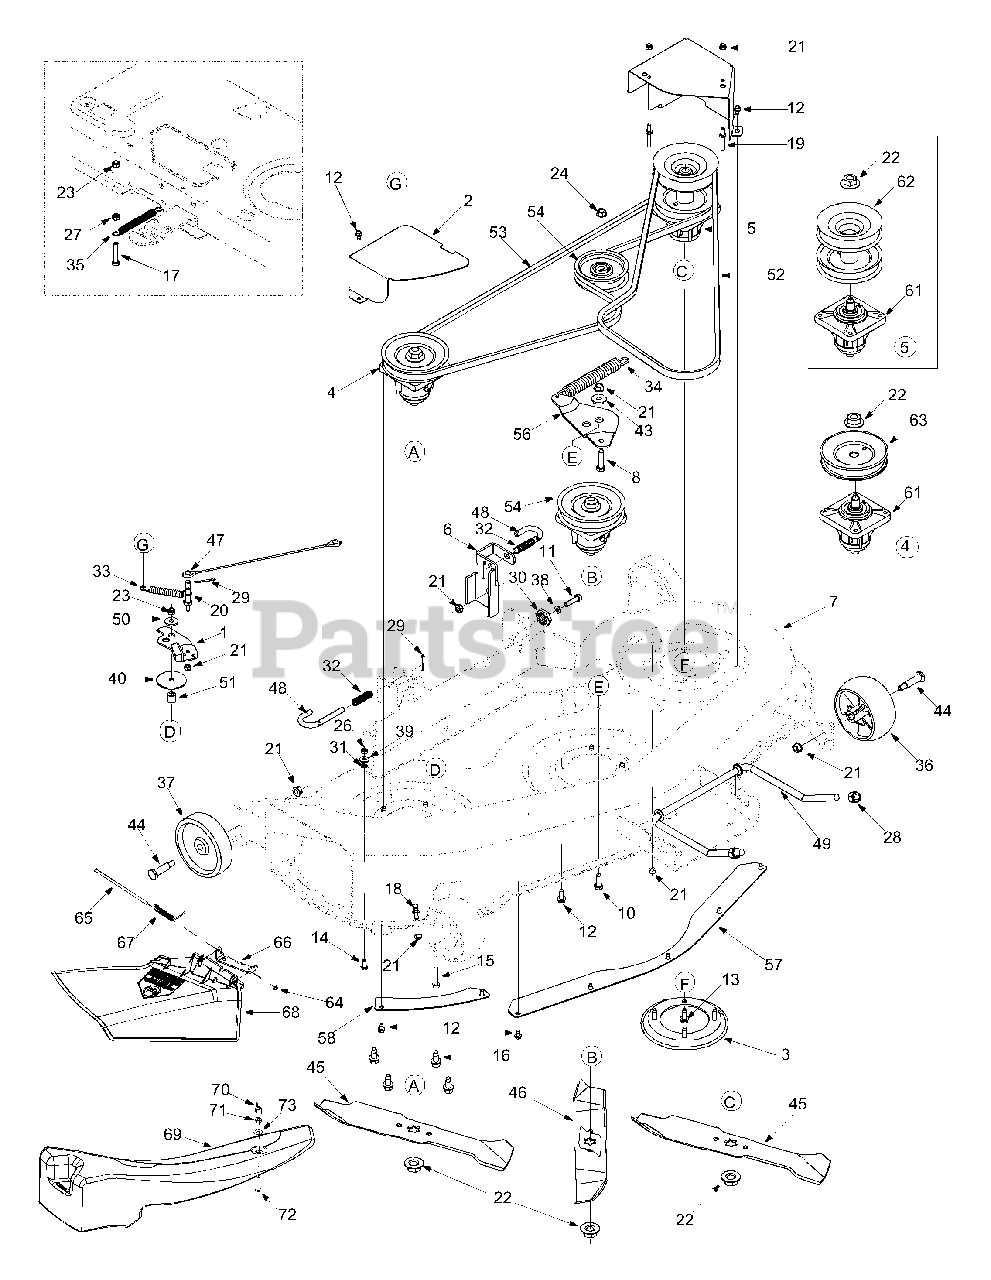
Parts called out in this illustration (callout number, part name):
1	Deck Brake Assembly
5	Spindle Assembly: Double Pulley
9	Hex Bolt 1/4-20 x 2.0
10	Hex Bolt 3/8-16 x 1.0
11	Hex Bolt 5/16-18 x 1.25
12	TT Screw 1/4-20 x 0.5
13	TT Screw 5/16-18 x 0.875
14	Hex Bolt 1/4-20 x 0.620
15	Hex Bolt 5/16-18 x 1.5
16	LD Screw 5/16-18 x 0.75
17	Hex Bolt 5/16-18 x 1.75
18	Grass Catcher Pin
19	Belt Guard Pin
20	Pin 1/4-20
21	Hex Lock Nut 1/4-20
22	Flange Nut
23	Lock Nut 5/16-18
24	Flanged Lock Nut 3/8-16
25	Hex Nut M16
26	Hex Nut 1/4-20
27	Hex Nut 5/16-18
28	Lock Nut 1/2-13
29	Cotter Pin
30	Gear: Deck Adjustment
31	Push Nut
32	Compression Spring
33	Extension Spring
34	Extension Spring
35	Extension Spring
36	Deck Wheel 5.0 dia. Ball
37	Deck Wheel 5.0 x 1.38
38	Lock Washer
39	Bell Washer
40	Flat Washer
41	Lock Washer
43	Shoulder Spacer
44	Shoulder Screw 3/8-16
45	Blade: 16.28" Three in One
46	Blade: 14.88" Three in One
47	Cable: Bracket
48	Rod: Deck Release Handle
49	Rod: Front Adjustment
50	Shoulder Spacer
51	Spacer
52	Belt: V Type (two belt deck design)
53	Belt: V Type (two belt deck design)
54	Idler Pulley
55	Label: Danger Tag
59	Chute Stop
61	Spindle Housing
62	Deck Pulley: Double
63	Deck Pulley
64	Speed Nut
65	Hinge Pin
66	Mounting Bracket
67	Torsion Spring
68	Chute Deflector: Side Discharge
69	Mulch Plug
70	Wing Nut
71	Hex Nut
72	Machine Screw
73	Flat Washer
